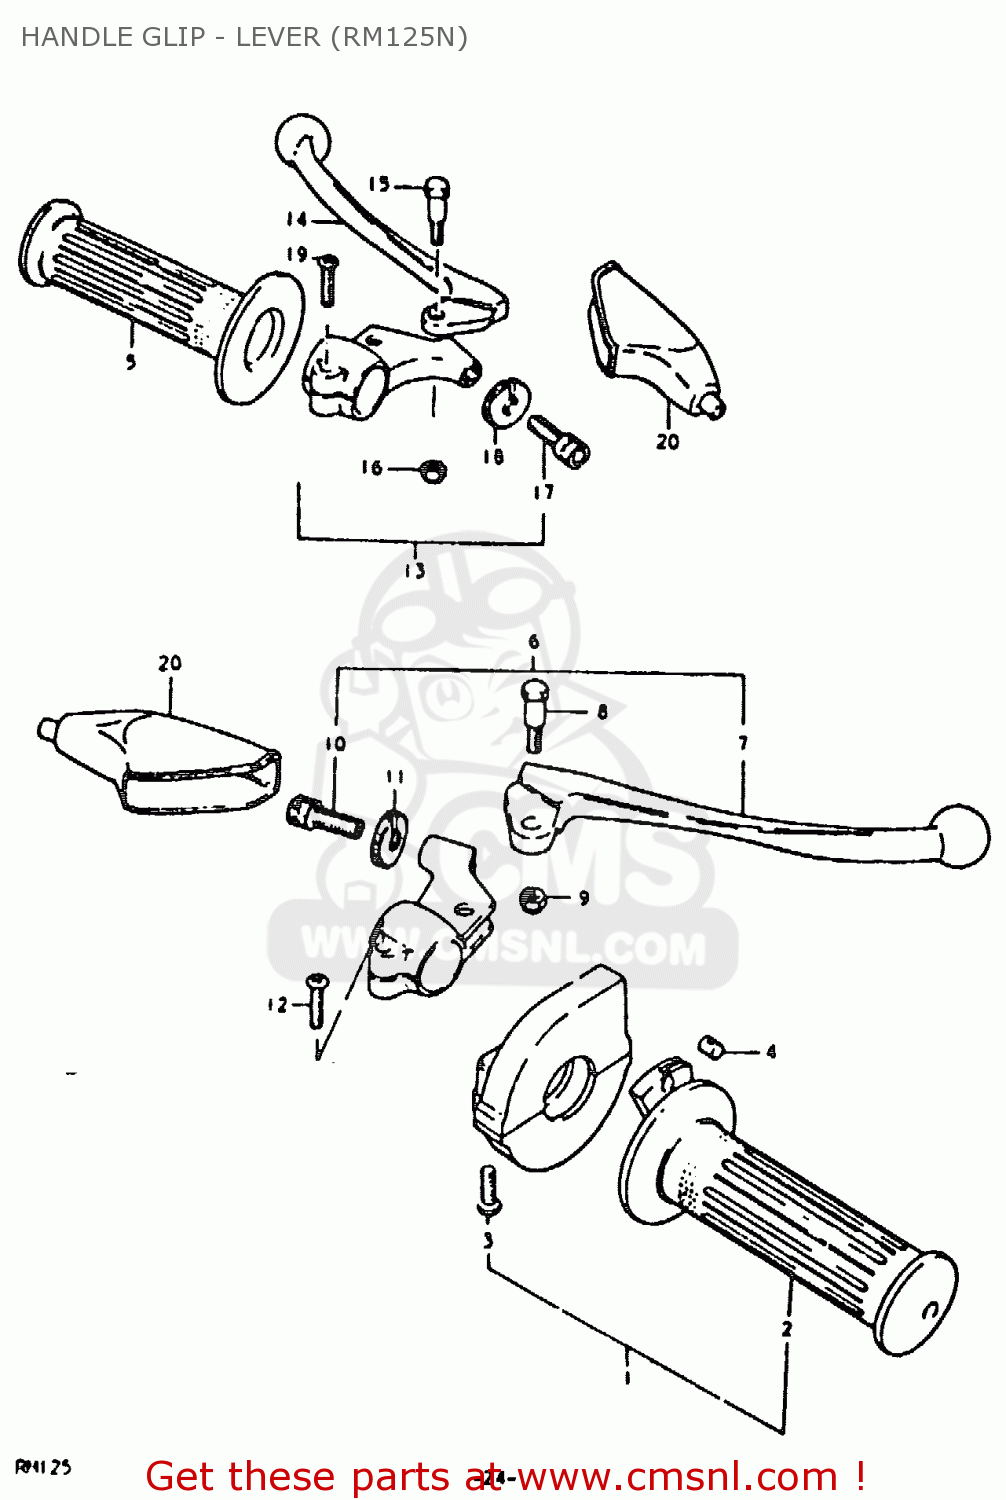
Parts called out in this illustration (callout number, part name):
1	GRIP ASSY,THROTTLE
2	GRIP,THROTTLE
3	SCREW
4	PIECE,THROTTLE END
5	GRIP,LEFT
6	LEVER ASSY,BRAKE
7	LEVER,BRAKE
8	BOLT,LEVER
9	NUT 6MM
10	ADJUSTER,CABLE
11	NUT,CABLE ADJUSTER
12	SCREW
13	LEVER ASSY,CLUTCH
14	LEVER,CLUTCH
15	BOLT,LEVER
16	NUT 6MM
17	ADJUSTER,CABLE
18	NUT,CABLE ADJUSTER
19	SCREW
20	COVER,CLUTCH LEVER
